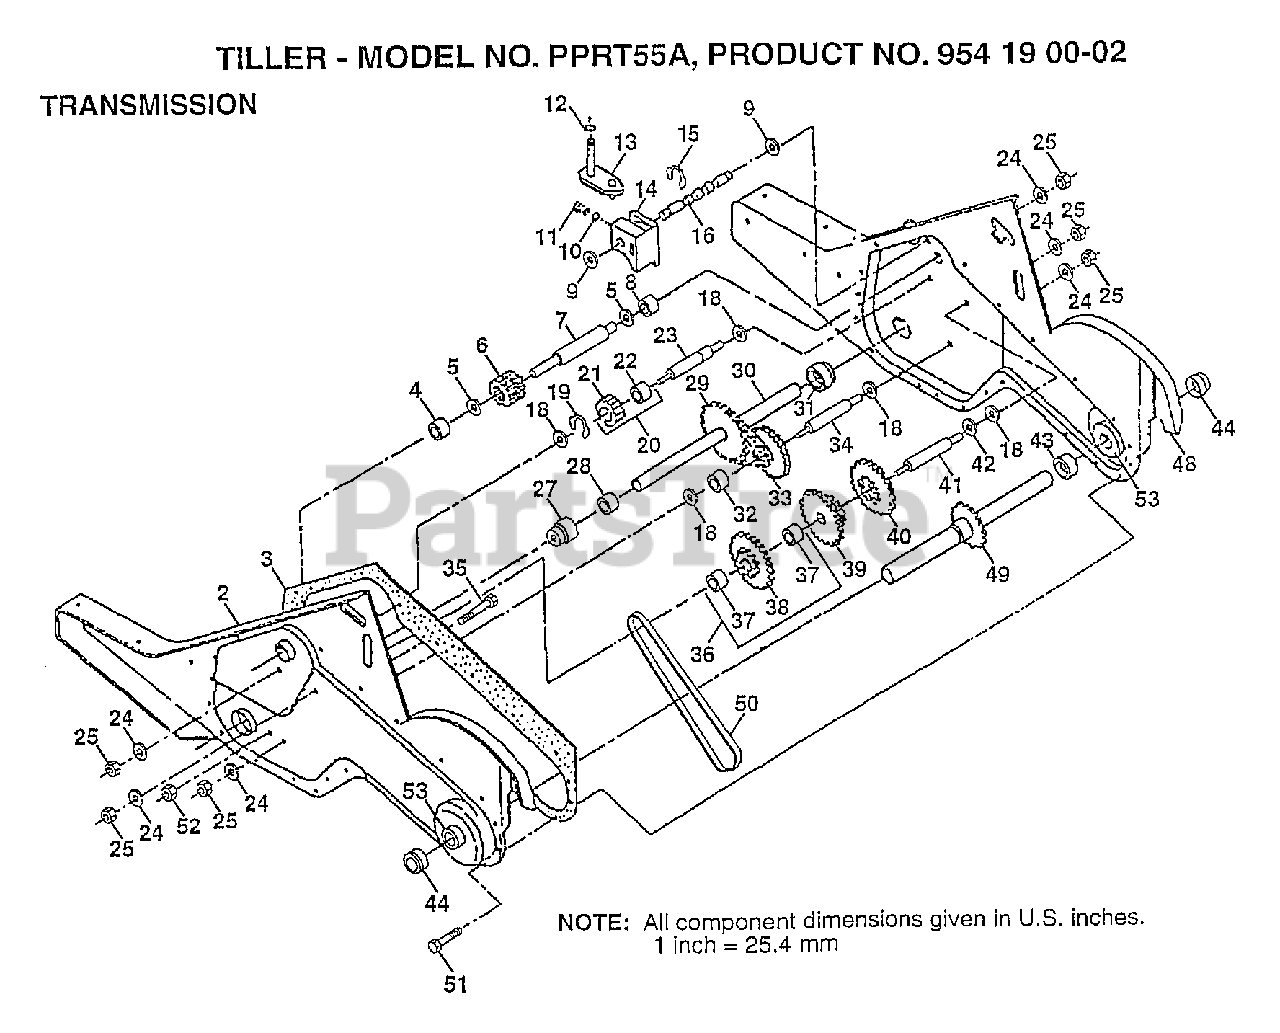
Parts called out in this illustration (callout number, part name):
2	GEARCASE LH W/BRG
3	GASKET, GEARCASE
4	NEEDLE BRNG LT
5	"T, BEARING"
6	GEAR PINION INPUT
7	"SHAFT.INPUT.""D"""
8	BEARING NEEDLE
9	WASHER SEAL
11	SPRING SHIFT FORK
13	BRACKET ASM SHIFT
14	SHIFT FORK TI
15	KLIP RING
16	SHAFT.SHIFTER
18	WASHER
19	KLIP RING
20	GEAR ASSEMBLY
21	GEAR REVERSE IDLER
22	NEEDLE BEARING TI
23	SHAFT, REVERSE IDLER
24	LOCKWASHER
25	NUT.ASF.HEX.7/16
27	BEARING.SHAFT.LH.
30	GROUND SHAFT ASSY
31	BEARING.SHAFT.RH.
33	SPROCKET AND GEAR ASSEMBLY
34	SHAFT REDUCTION
35	SCREW WHIZ LOCK
36	SPROCKET.ASM.W/BR
37	BEARING NEEDLE
39	GEAR CLUSTER RED 1ST AND 2ND
40	GEAR REVERSE
41	REDUCTION SHFT TI
42	BRNG RACE
44	SEAL ASM-OIL
48	GEARCASE RH W/BRG
49	TINE SHAFT
50	CHAIN ROLLER
51	SCREW
52	NUT.HEX.5/16-18
53	KIT BEARING
